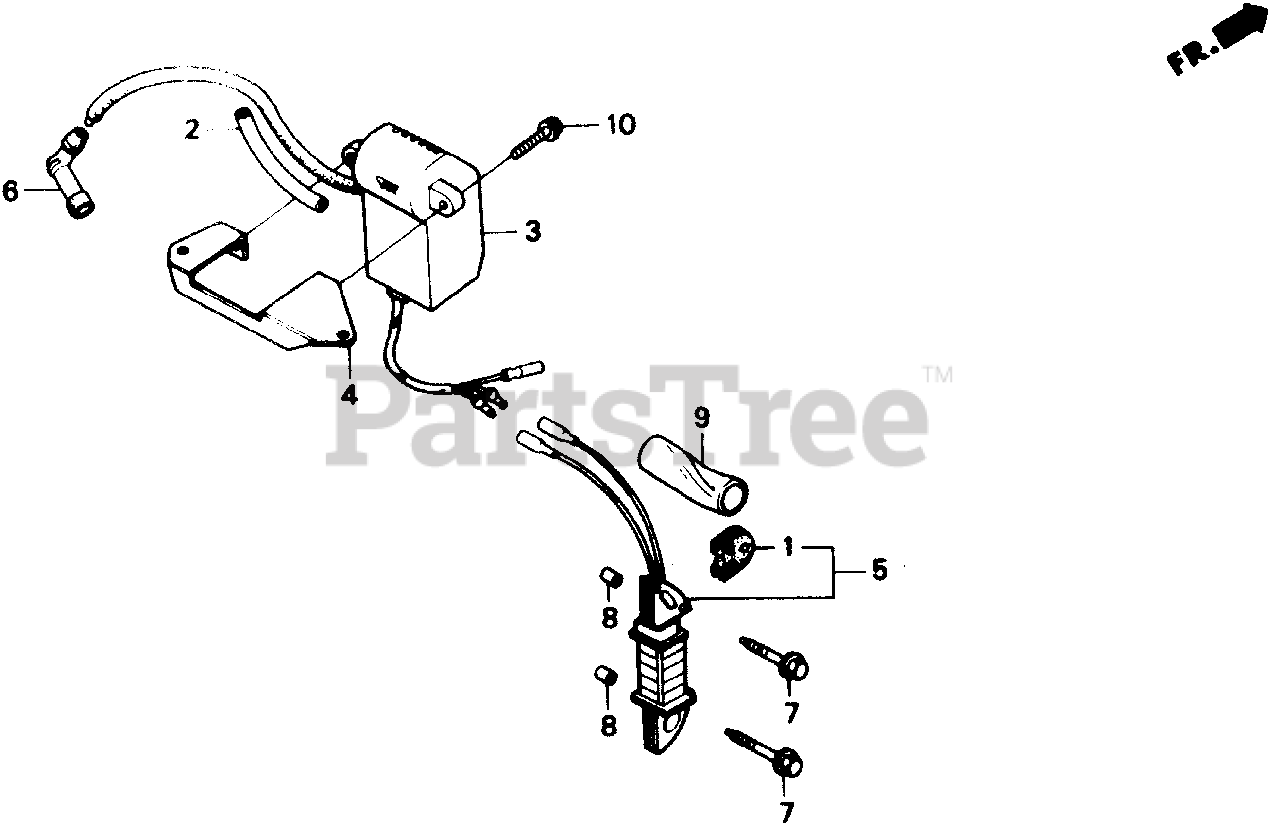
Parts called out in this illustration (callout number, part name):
1	GROMMET, WIRE
2	TUBE, IGNITION RUBBER
3	MODULE, IGNITION CONTROL (CDI) (NOT AVAILABLE)
4	STAY, IGNITION CONTROL MODULE
5	COIL ASSY., EXCITER
6	CAP ASSY., NOISE SUPPRESSOR (NOT AVAILABLE)
7	BOLT, FLANGE (6X28)
8	PIN A, DOWEL (8X14)
9	TUBE, VINYL (16X19X50)
10	BOLT, FLANGE (6X12)
